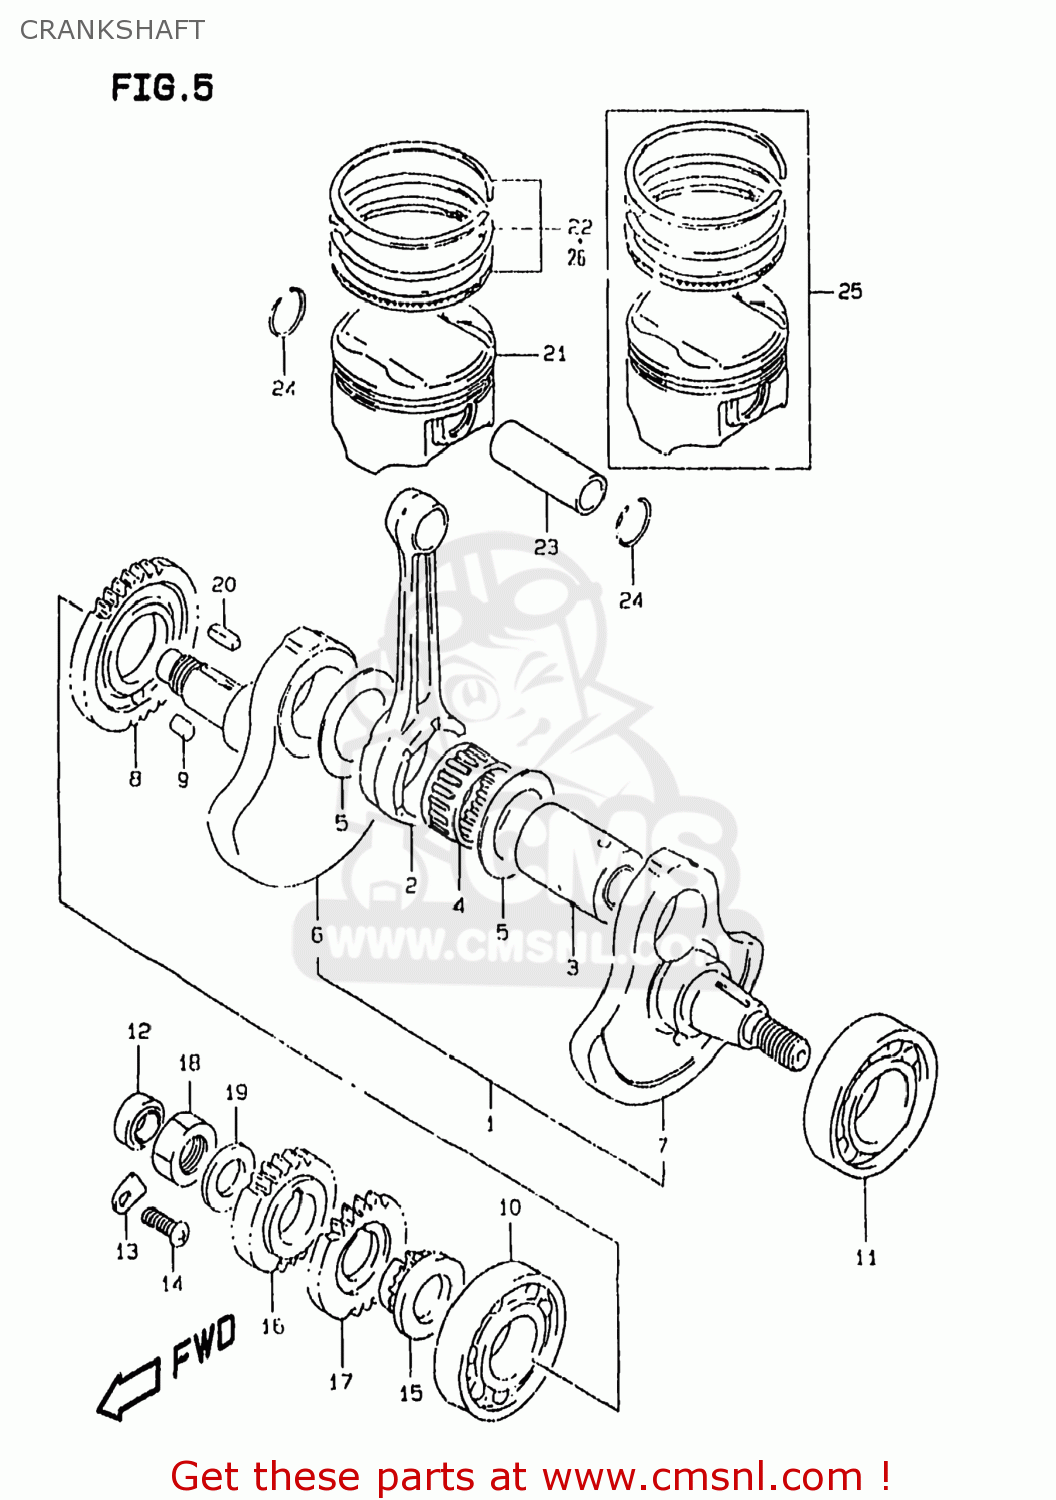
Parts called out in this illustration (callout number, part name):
1	CRANKSHAFT ASSY
2	ROD,CONNECTING
3	PIN COMP,CRANK
4	BEARING(34X43X22)
5	WASHER(34X52X1)
6	CRANKSHAFT,R
7	CRANKSHAFT,L
8	GEAR,CRANK BAL DRIVE(NT:37)
9	PIN
10	BEARING(30X72X19)
11	BEARING 35X72X17
12	SEAL,OIL(14X24X6)
13	RETAINER,BEARING
14	SCREW
15	SPROCKET,CAM CHAIN DRIVE
16	GEAR,PRIMARY DRIVE
17	GEAR,OIL PUMP DRIVE (NT
18	NUT
19	WASHER
20	KEY
21	PISTON
22	RING SET,PISTON
23	PIN,PISTON
24	CIRCLIP,PISTON PIN
25	PISTON SET(OS:0.5)
26	RING SET,PISTON(OS:1.0)
